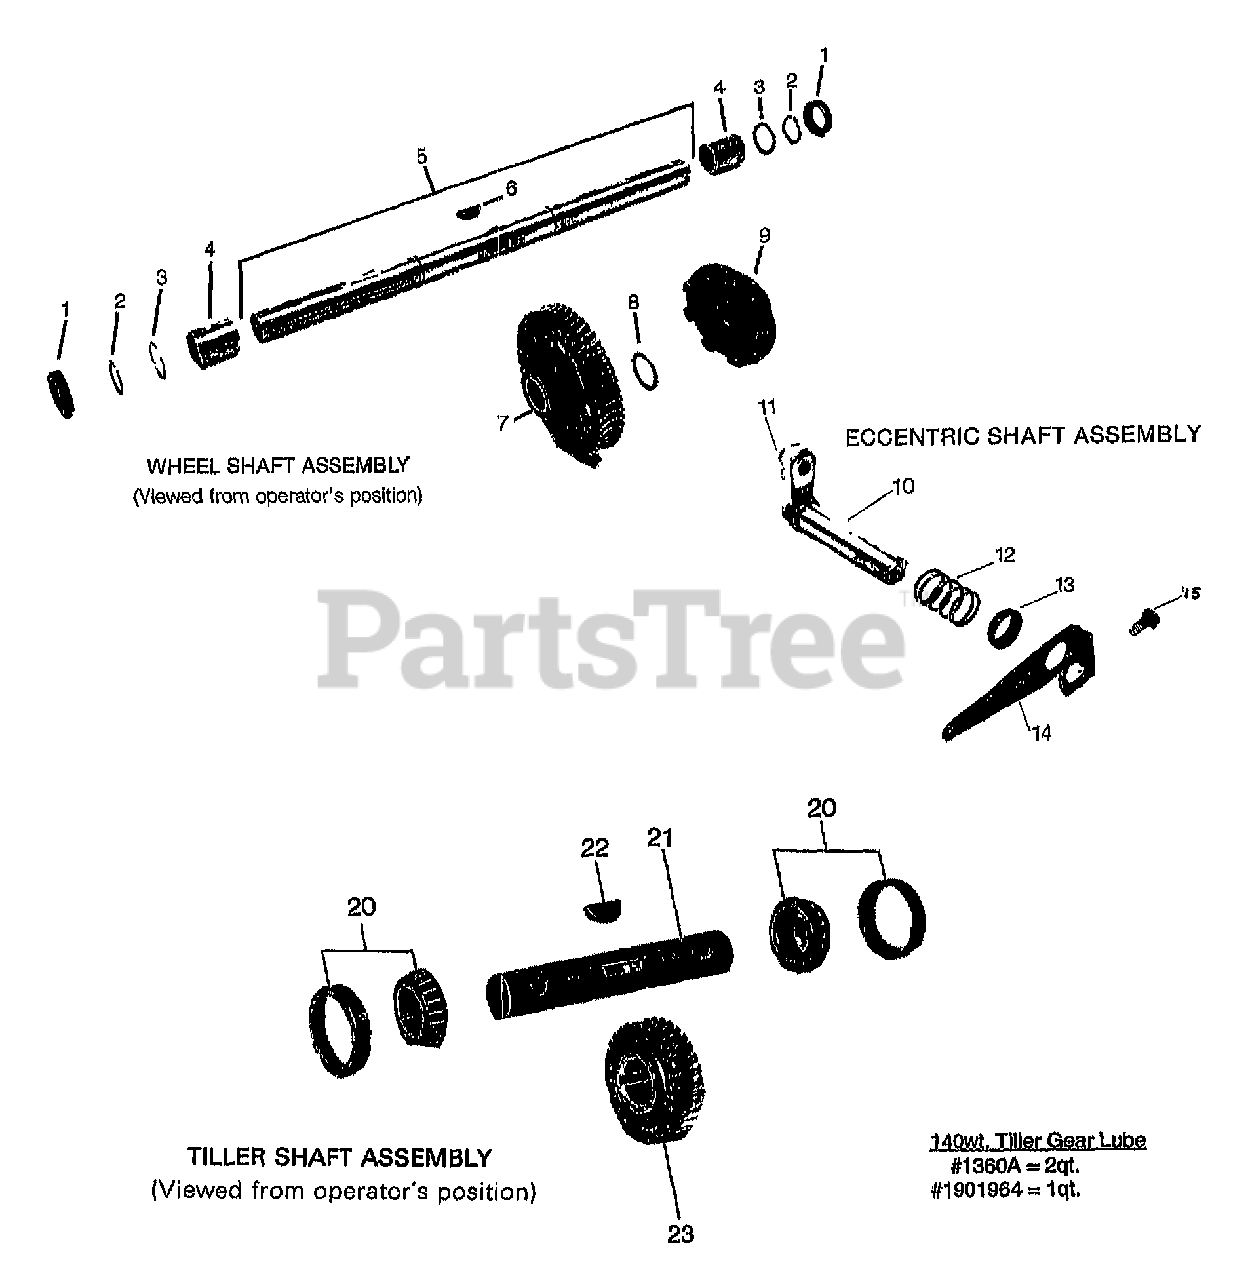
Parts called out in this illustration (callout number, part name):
1	SEAL-OIL WHEELSHAFT
2	RING-HEAVY EXT .906 ID
3	SHIM-1.375X1.015X.062
3	SHIM-1.375X1.015X.03
3	SHIM-1.375X1.015X.015
3	SHIM-1.375X1.015X.01
4	BUSHING-1.25X1.005X1.5
5	ASSM-WHEEL SHAFT W/KEY #9373
6	KEY-HI PRO .25X1.312
7	GEAR-WORM 46 TEETH MACH
8	WASHER-1.468X1.016X.062
9	CLUTCH-MACH
10	WELD-ECCENTRIC
11	PIN-.375 X .72
12	SPRING-.850 X .875 LONG
13	SEAL-OIL ECCENTRIC
14	LEVER-CABLE ADJ PNT
15	SCR-HH 1/4-20X.5 GR5 YEL
20	BEARING CUP & CONE
21	SHAFT W/KEY (TILLER) #1104
22	KEY-WOODRUFF .25X1.12
23	GEAR-TILLER MACH
